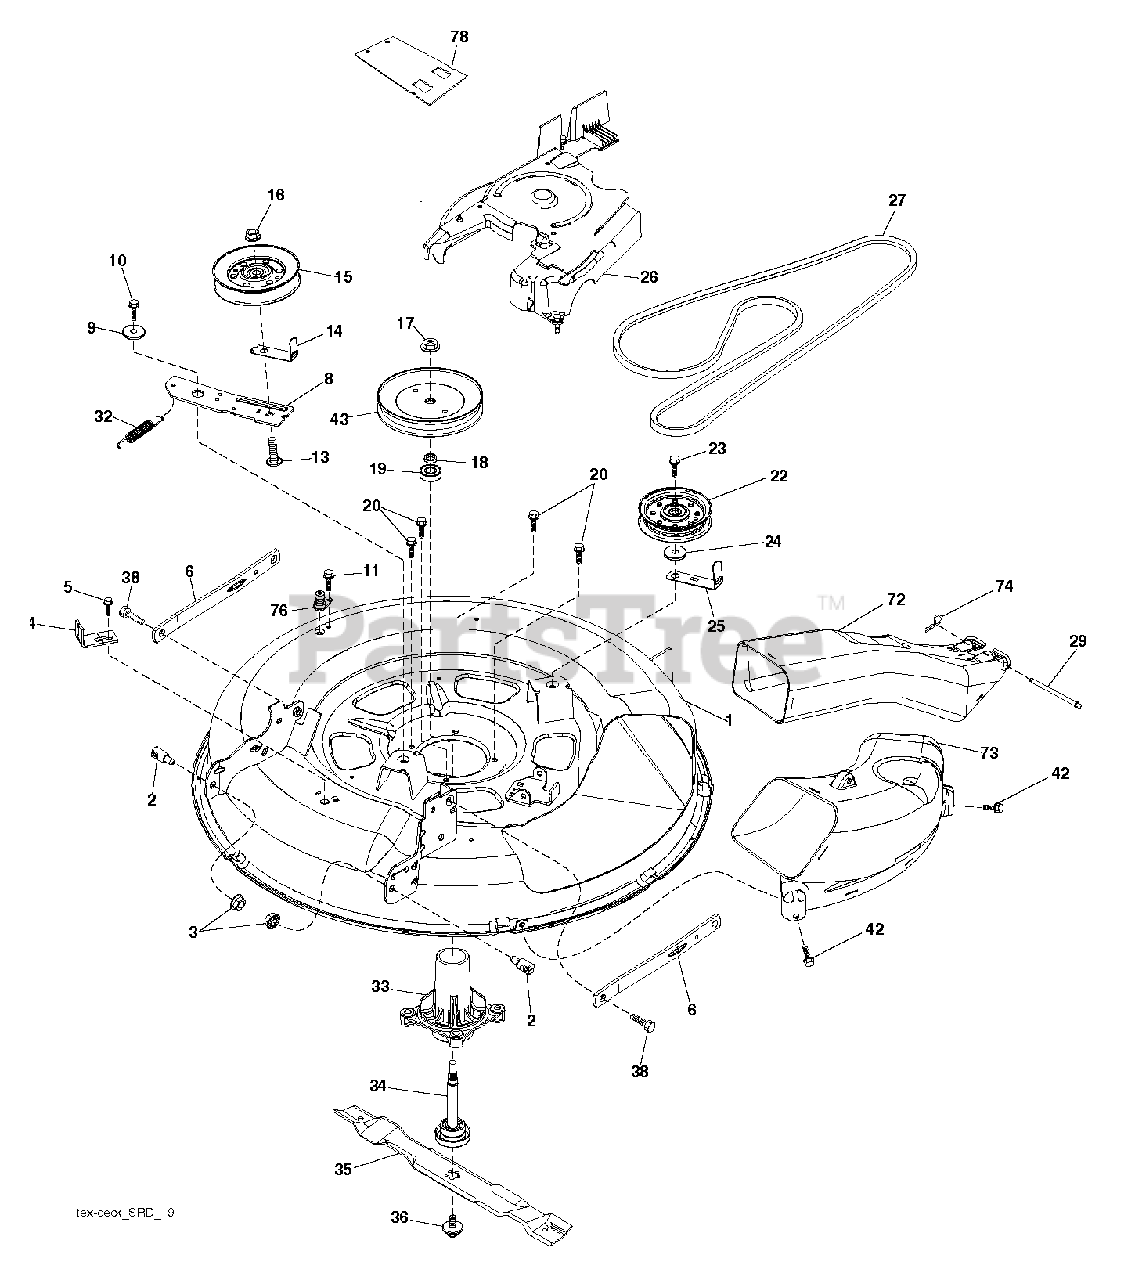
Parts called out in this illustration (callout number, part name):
2	STUD.FASTNER.W/ANTI-ROTATE
3	NUT LOCK HEX FLANGE 5/16-18
5	BOLT.5/16HEX.WHS.HD
6	ARMS.SUSP.MOWER.REAR.SRD
9	SPACER.RETAINER
10	SCREW 3/8-16X1
11	SCREW.1/4-20X5/8
13	BOLT.3/8-16X1.50
14	KEEPER, BELT IDLER
15	PULLEY.IDLER.4.25
16	NUT LOCK FLG 3/8-16 UNC
17	NUT.FLANGE.LOCK.TOP
18	WASHER.SPACER.MANDREL
20	SCREW, WASHER HEAD
22	PULLEY.IDLER.FLAT.UNPLATED
23	SCREW LT
27	V-BELT.DRIVE.MOWER.30"
32	SPRING.MOWER.DRIVE.ELECTRIC
33	HOUSING MANDREL
34	SHAFT.ASM.MDRL.N/GREASE.38
35	BLADE.MOWER.BAGGING.30"
36	BOLT.WASHER.ASM.7/16-2
38	BOLT.SHOULDER
42	SCREW, 3/8-16X3/4
43	PULLEY, MANDREL 6.5 PD
74	RETAINER-SPRNG RB
76	PORT.WASHOUT
